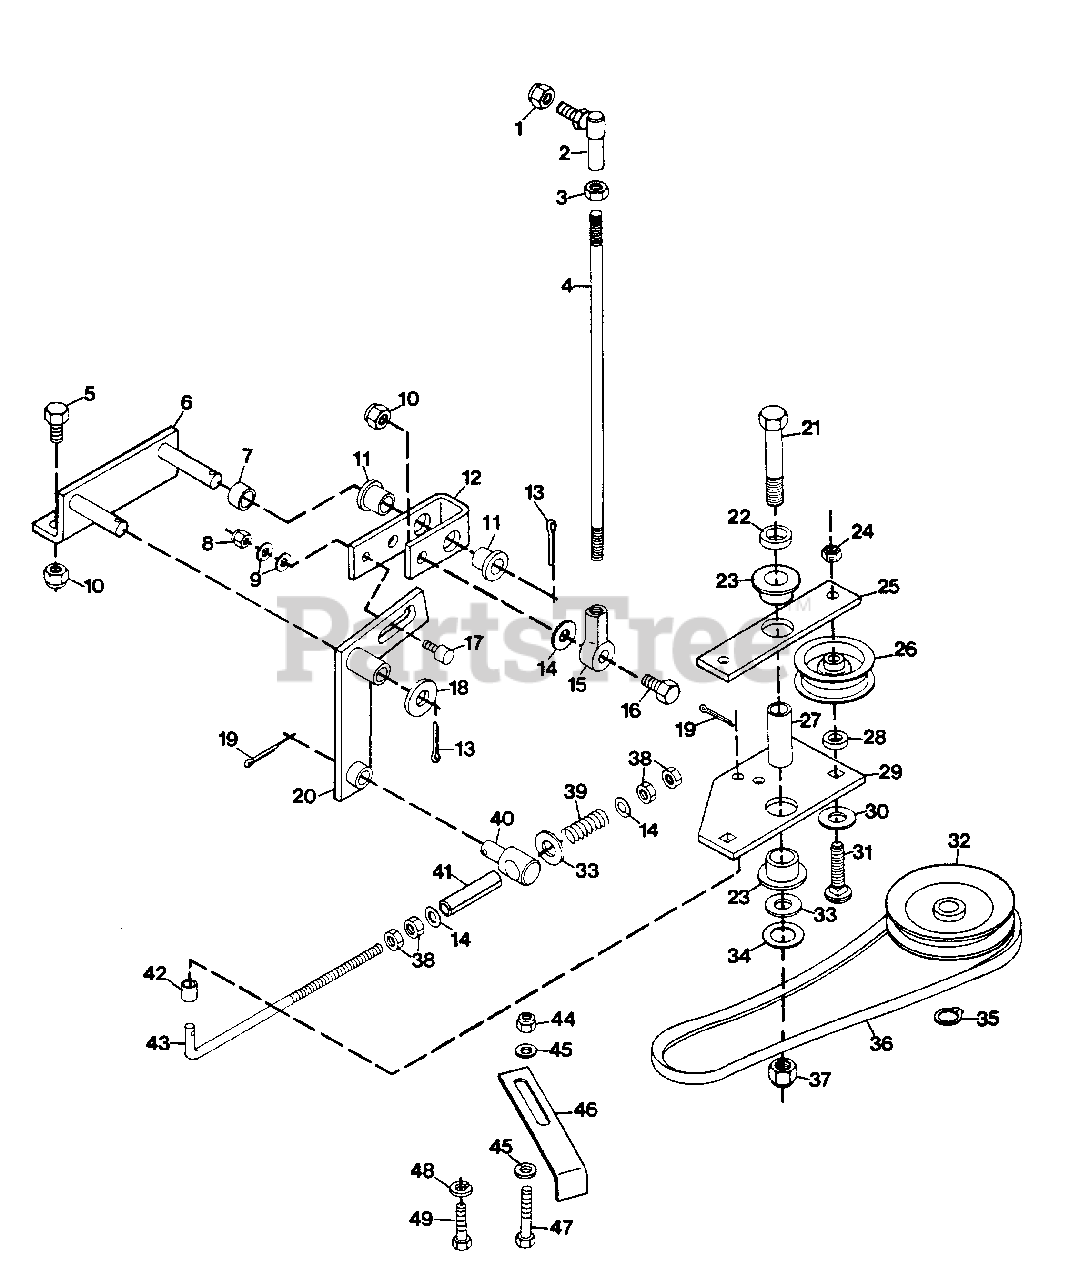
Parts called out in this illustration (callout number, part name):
1	NUT, LOCK 3/8-24
2	BALL JOINT, STEERING
3	NUT, HEX 3/8-24
4	ROD, CLUTCH ACTUATING
5	BOLT, HEX 3/8-16X1.00
6	WLDMNT, FWD-REV CONTROL BRACKET
7	BUSHING
8	NUT, LOCK 1/4-28
9	WASHER, FLAT .281X.625X.065
10	NUT, LOCK 3/8-16
11	BUSHING, .513X.750X.625
12	LEVER, FWD-REV ACTIVATING
13	PIN, COTTER .125X.75
14	WASHER, FLAT .406X.812X.065
15	ROD END, SPHERICAL BEARING
16	BOLT, HEX 3/8-16X1.25
17	ROLLER, CLUTCH CAM
18	WASHER, FLAT .531X1.062X.095
19	PIN, COTTER .09X.75
20	WELDMENT, FWD-REV CAM
21	BOLT, HEX 1/2-13X3.00
22	SPACER
23	BUSHING, NYLON .76X1X.6 FLANGE
24	NUT, LOCK 3/8-16
25	PLATE, IDLER
26	SHEAVE, IDLER
27	SPACER
28	SPACER, IDLER .406X.750X.188
29	PLATE, IDLER
30	WASHER, FLAT .531X1.063X.095
31	BOLT, 3/8-16X1.75 RD HD SQ NK
32	SHEAVE, TRANSMISSION
33	WASHER, FLAT .531X1.250X.100
34	RACE, BEARING THRUST
35	RING, RETAINING
36	BELT, ENGINE-TRANSMISSION DRIVE
37	NUT, LOCK 1/2-13
38	NUT, HEX 5/16-18
39	SPRING, COMP. 2X.720X15.5 RATE
40	PIVOT
41	SLEEVE, SPRING
42	BUSHING, .375X.500X.437
43	ROD, CLUTCH
44	NUT, LOCK 5/16-18
45	WASHER, FLAT .344X.688X.065
46	GUIDE, V-BELT
47	BOLT, HEX 5/16-18X1.75
